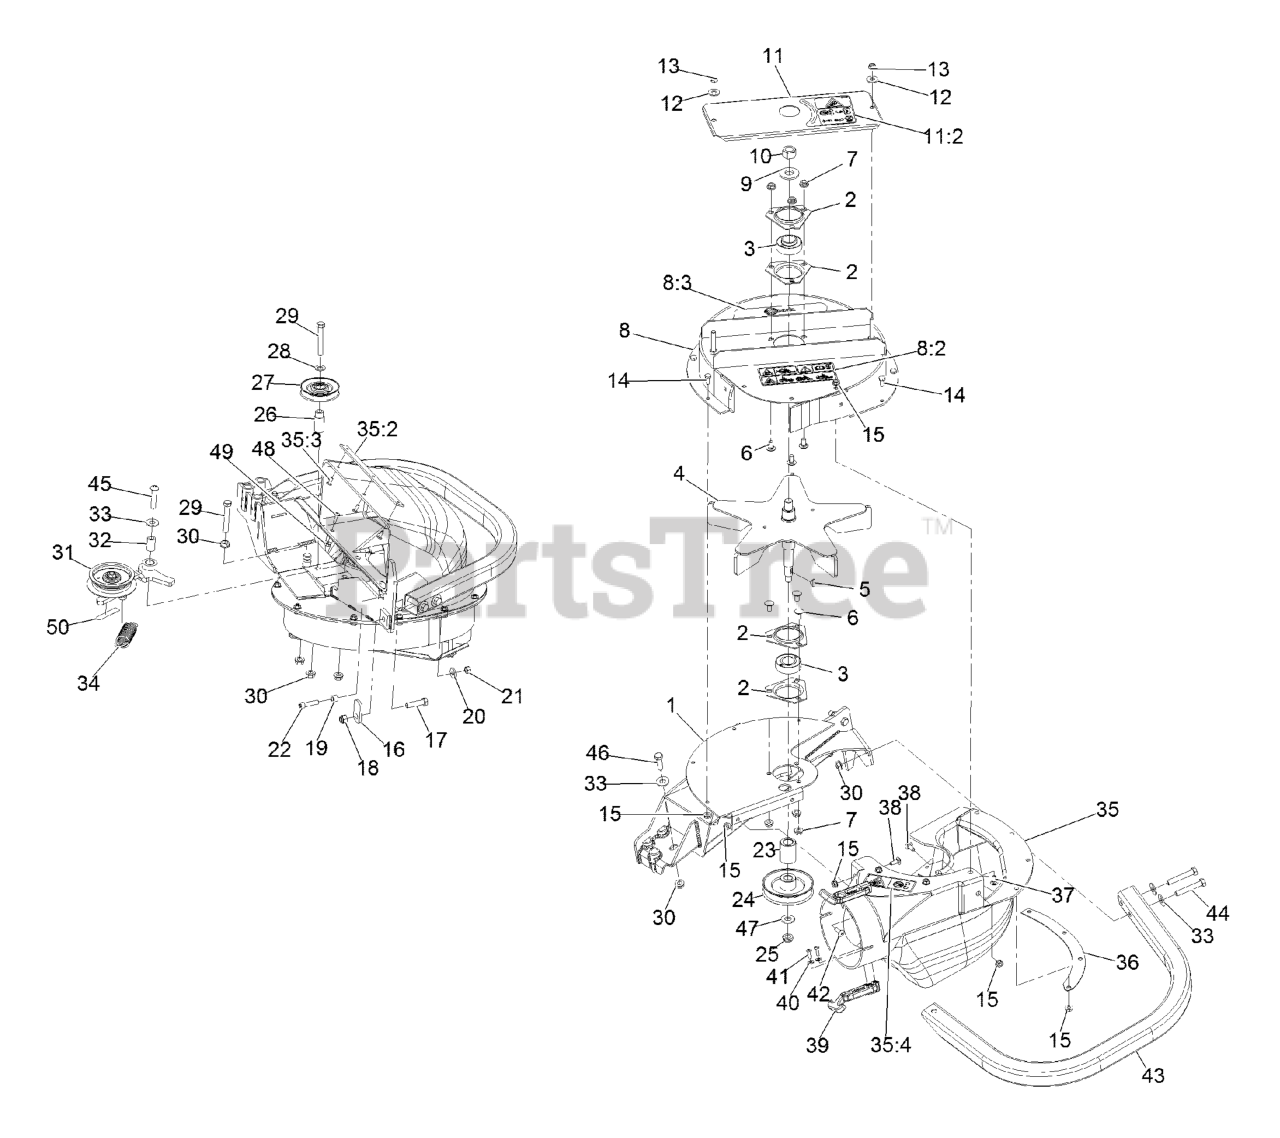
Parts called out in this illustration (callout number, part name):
1	Frame- Blower [black]
2	HOUSING-FLANGE
3	BEARING
4	IMPELLER
5	KEY-WOODRUFF
6	SCREW-CARR
8	UPPER-HOUSING W/DECAL
8:2	Decal-Ultravac S-Series
8:3	DECAL-WARNING
9	WASHER-SPRING
10	NUT-HEX
11	COVER-BEARING W/DECAL
11:2	DECAL-WARNING
12	WASHER-FLAT
13	NUT-LOCK, NI
14	SCREW-HH
16	LATCH-CATCHER, GRASS
17	SCREW-HH
18	NUT-LOCK, NI
19	BUSHING, LOCATOR
20	WASHER-SPRING
21	NUT-HEX
22	SCREW-HSH
24	SHEAVE-BLOWER
25	NUT-LOCK, NI
27	IDLER-INSIDE
28	WASHER-FLAT
29	SCREW-HH
30	NUT-HHF, WHIZ
31	ASM, IDLER
32	BUSHING-PIVOT, IDLER
33	WASHER-FLAT
34	SPRING-IDLER
35	ASM,BLOWER CHUTE LHP
35:2	PLATE-REINFORCEMENT
35:3	RIVET-BLIND
35:4	Decal-Blower-Impeller Hazard
36	PLATE-BACKING, BLOWER
37	SCREW-CARR
38	BOLT-CARR
39	LATCH-RUBBER
40	WASHER-FLAT
41	SCREW-PPH
44	SCREW-HH
45	SCREW-HSBH
46	SCREW-HH
47	WASHER-FLAT
48	SCREW-HEAD, TRUSS
50	DECAL-WARNING
